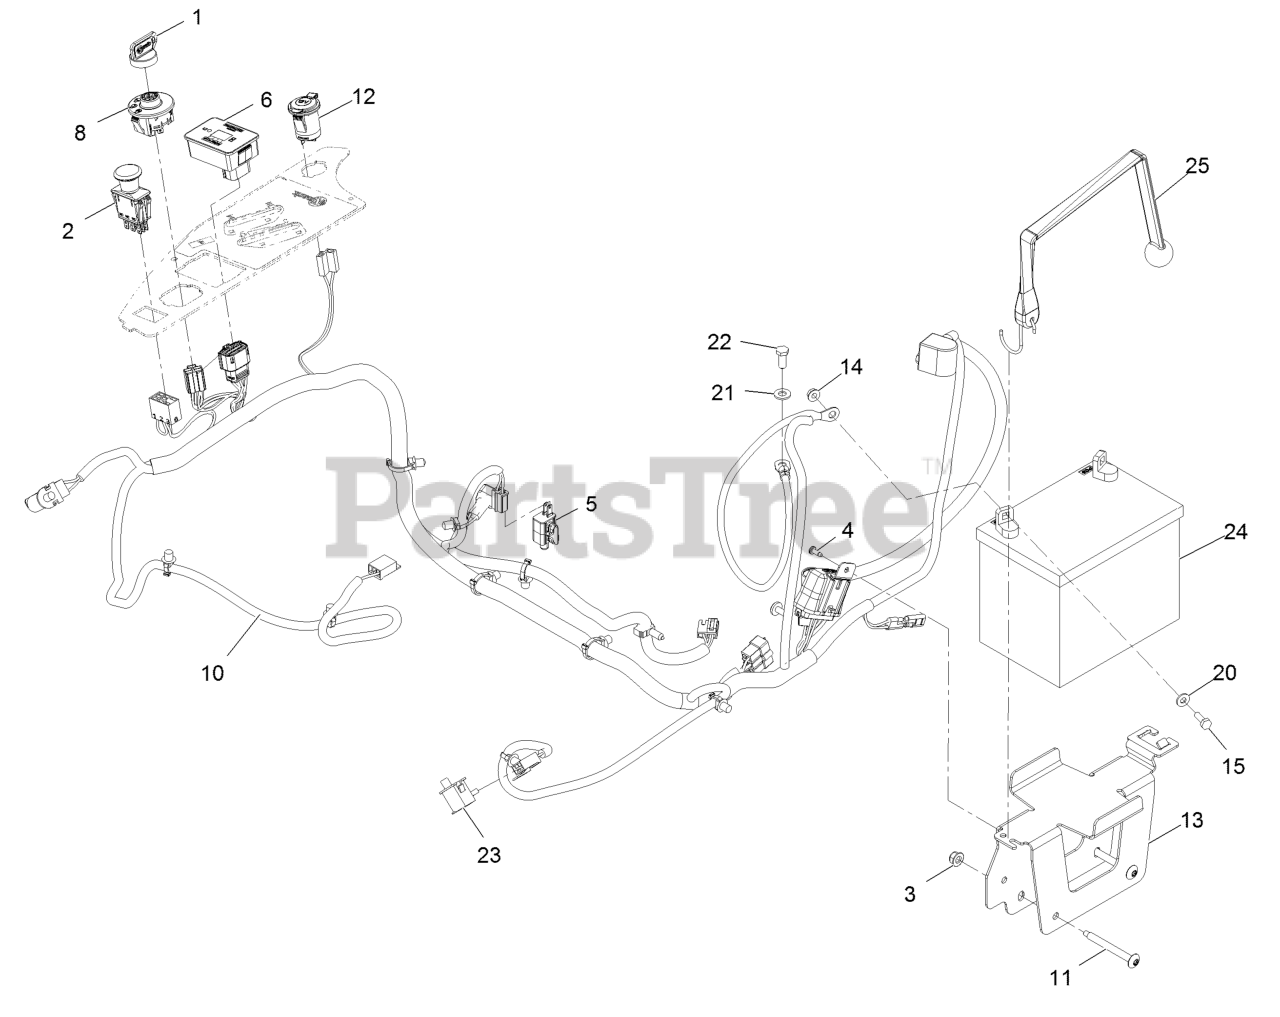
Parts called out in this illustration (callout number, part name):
1	Key-Ignition
1	Key-Exmark Logo
2	Switch-PTO
3	Nut-Nyloc 5/16-18 Flg
4	Screw-Tph #10-24 X 1/2 Tf
6	Module ASM
8	Switch-Ignition
10	Harness-Wire
11	Screw-Truss HD 5/16-18 X 2 3/4 Torx Plus
12	Port-Power, 12V
13	Tray-Battery
14	Nut-Whizlock 1/4-20
15	Screw-HH 1/4-20 X 3/4
20	Washer-1/4 SAE
22	Screw-HH M8-1.25 X 20Mm
24	Battery (300 CCA, Wet)
25	Strap-Bungee
